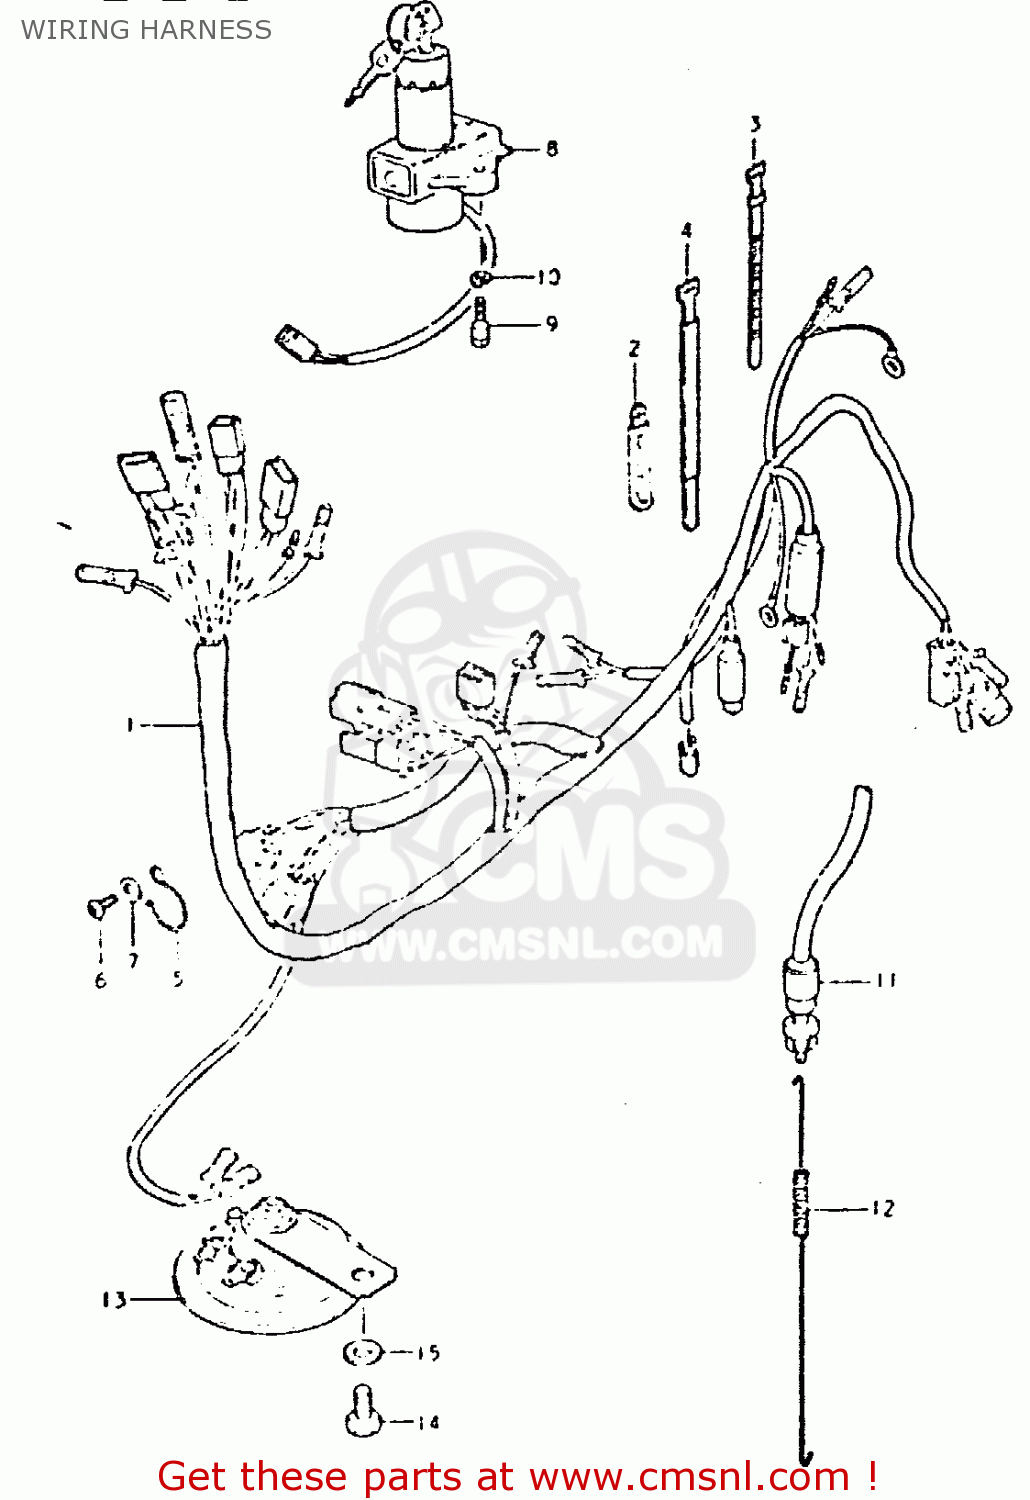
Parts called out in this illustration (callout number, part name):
1	WIRING HARNESS
2	CLAMP
3	CLAMP(L:80)
4	CLAMP
5	GUIDE,WIRING HARNESS
6	SCREW 6X12
7	WASHER 6MM
8	LOCK ASSEMBLY,STEERING
9	BOLT
10	LOCK WASHER
11	SWITCH ASSEMBLY,STOP LAMP
12	SPRING
13	HORN ASSEMBLY
14	BOLT 8X12
15	WASHER
